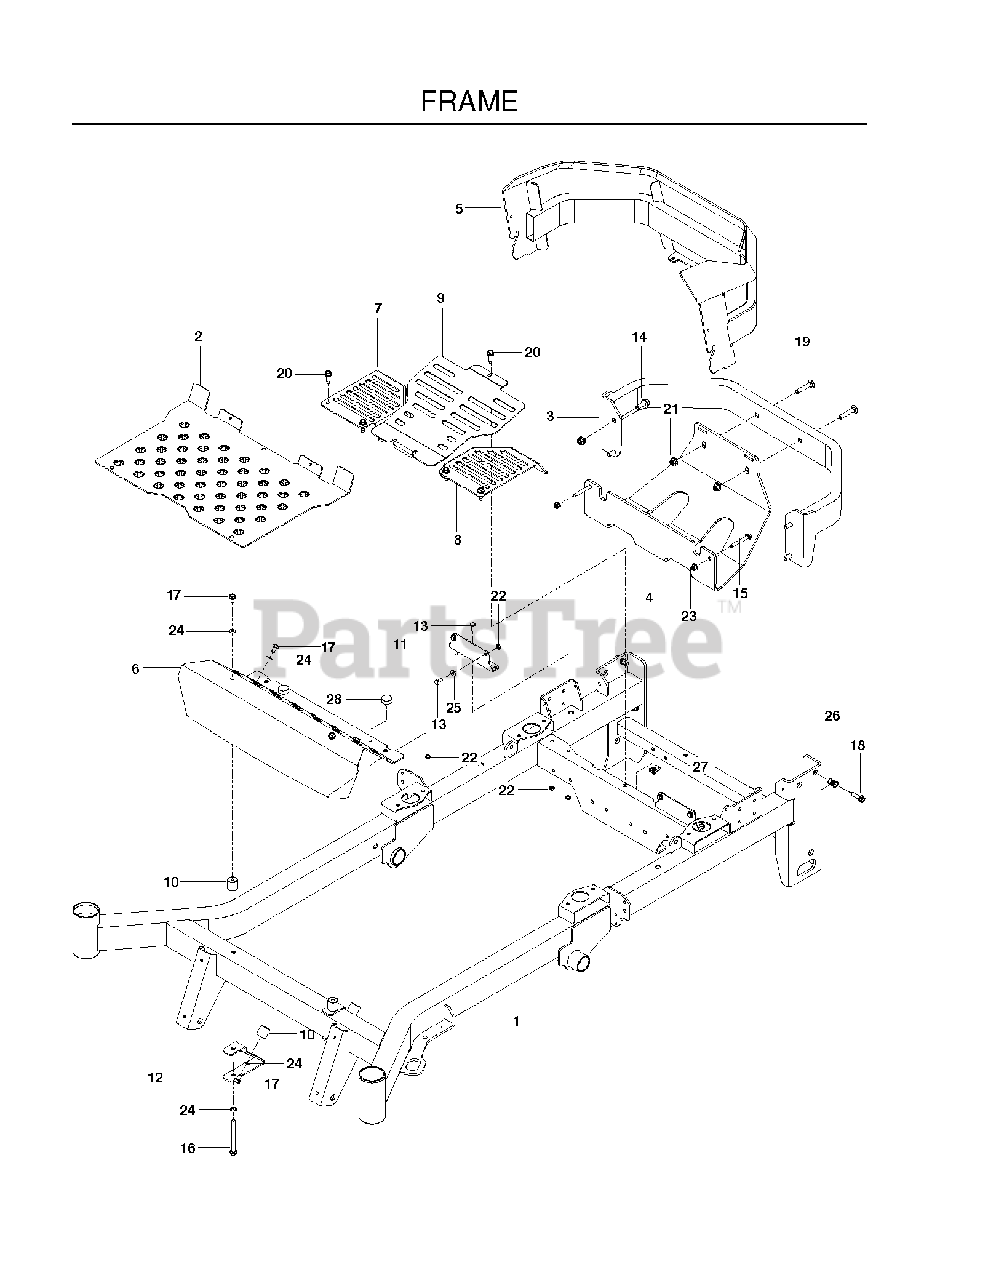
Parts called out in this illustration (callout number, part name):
1	FRAME W/DECALS, PZ
2	PLATE FLOOR PAN ORANGE
3	BUMPER, REAR, ORG
4	PLATE.SKID.GRAY
5	GUARD.REAR.GRAY.ZTR
6	PLATE, FOOT REST, OR
7	COVER, FAN RT BLK
8	COVER, FAN LT BLK
9	COVER, CENTER BLK
10	MOUNT, F/F INSERT
11	MOUNT TANK BLK
12	BRACKET, REST MOUNT
13	HCS 1/4C X 5/8
14	HHFS 3/8-16 X 1 GRD 5 ZD
15	HHFS 5/16-18 X 2.25 GD 5
16	HHFS 5/16-18 X 3 3/4
17	SCR 5/16-18 X 1/2 SELFTAP ZN
18	HHFS 5/16-18 X 1.25 TPBLT GD 5
19	RHSNB 3/8C X 2
20	RP BLT 5/16-18 X 1 THRD FORM D
21	NUT 3/8-16 HEX FLG NYLOC ZD
22	JAM NUT 1/4C (2 2 PW01)
23	5/16-18 NYLOC FLANGE NUT
24	WASH 5/16 DISC SPRING ZD
25	WASHER 1/4 SAE
26	NUTSERT 5/16-18 THICK GRIP
27	U-CLIP 5/16-18 NUT RETAINER
28	BUMPER, 1/4-20 STUD, 1/4
